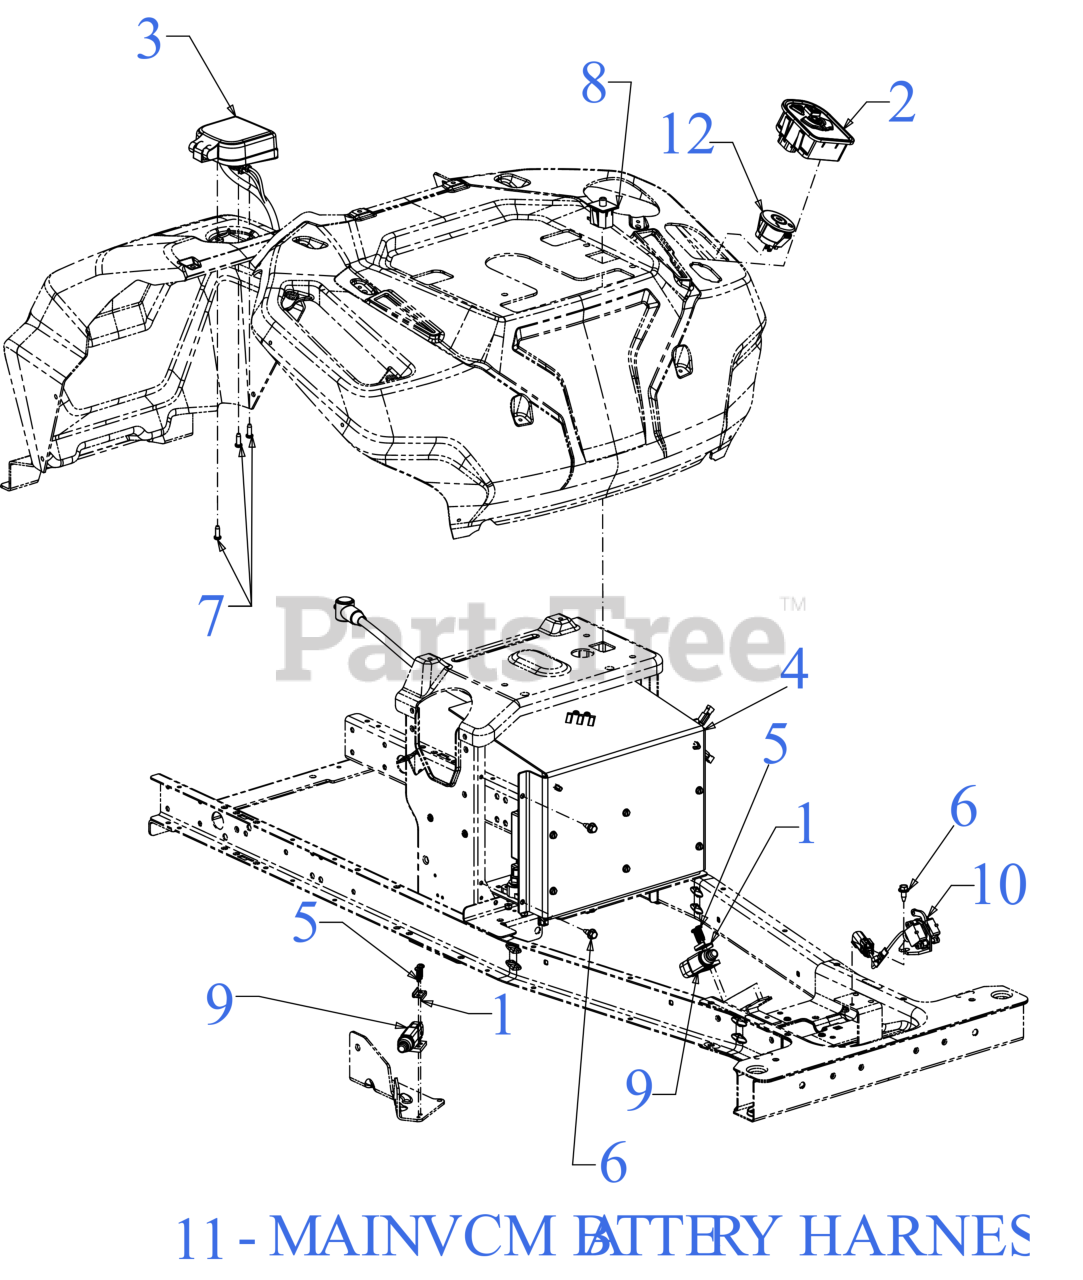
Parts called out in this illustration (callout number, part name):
1	PLATE-SWITCH
2	VCM MODULE
3	CHARGE PORT PLUG ASSEMBLY
4	MOTOR CONTROL PANEL
5	SCREW #
6	SCREW 1/4-20X.625
7	SCREW #12-16 x .625
8	SEAT SWITCH
9	PLUNGER SWITCH (NO/NO)
10	THROTTLE SENSOR (DUEL CLIP)
10	ROTARY SENSOR MAGNET
11	MAIN HARNESS (VCM HPD BATTERY)
12	KEY SWITCH (2 POSITION)
